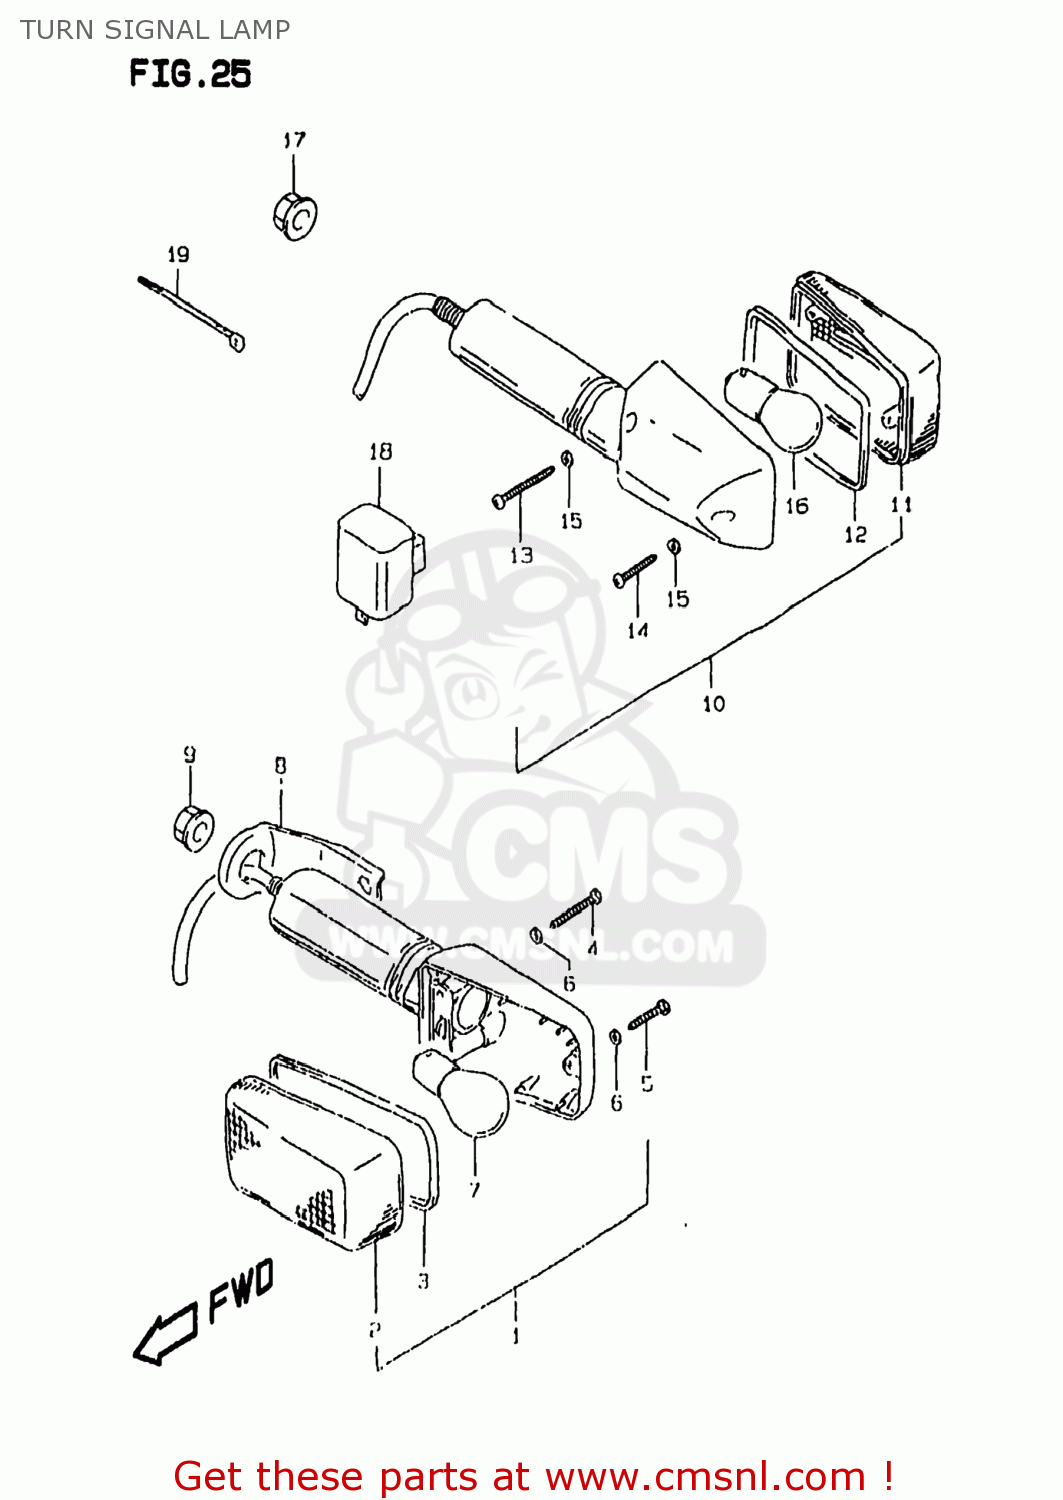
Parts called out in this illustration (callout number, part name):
1	LAMP ASSY,FR TURN SIGNAL
2	LENS
3	GASKET (NAS)
4	SCREW(3X30)
5	SCREW
6	GASKET (NAS)
7	BULB(12V21W)
8	BRACKET,FR TURNSIGNAL,R
9	NUT
10	LAMP ASSY,RR TURNSIGNAL,R
11	LENS
12	GASKET (NAS)
13	SCREW(3X30)
14	SCREW
15	GASKET (NAS)
16	BULB(12V21W)
17	NUT
18	RELAY ASSY,TURNSIGNAL
19	CLAMP(L:33)
